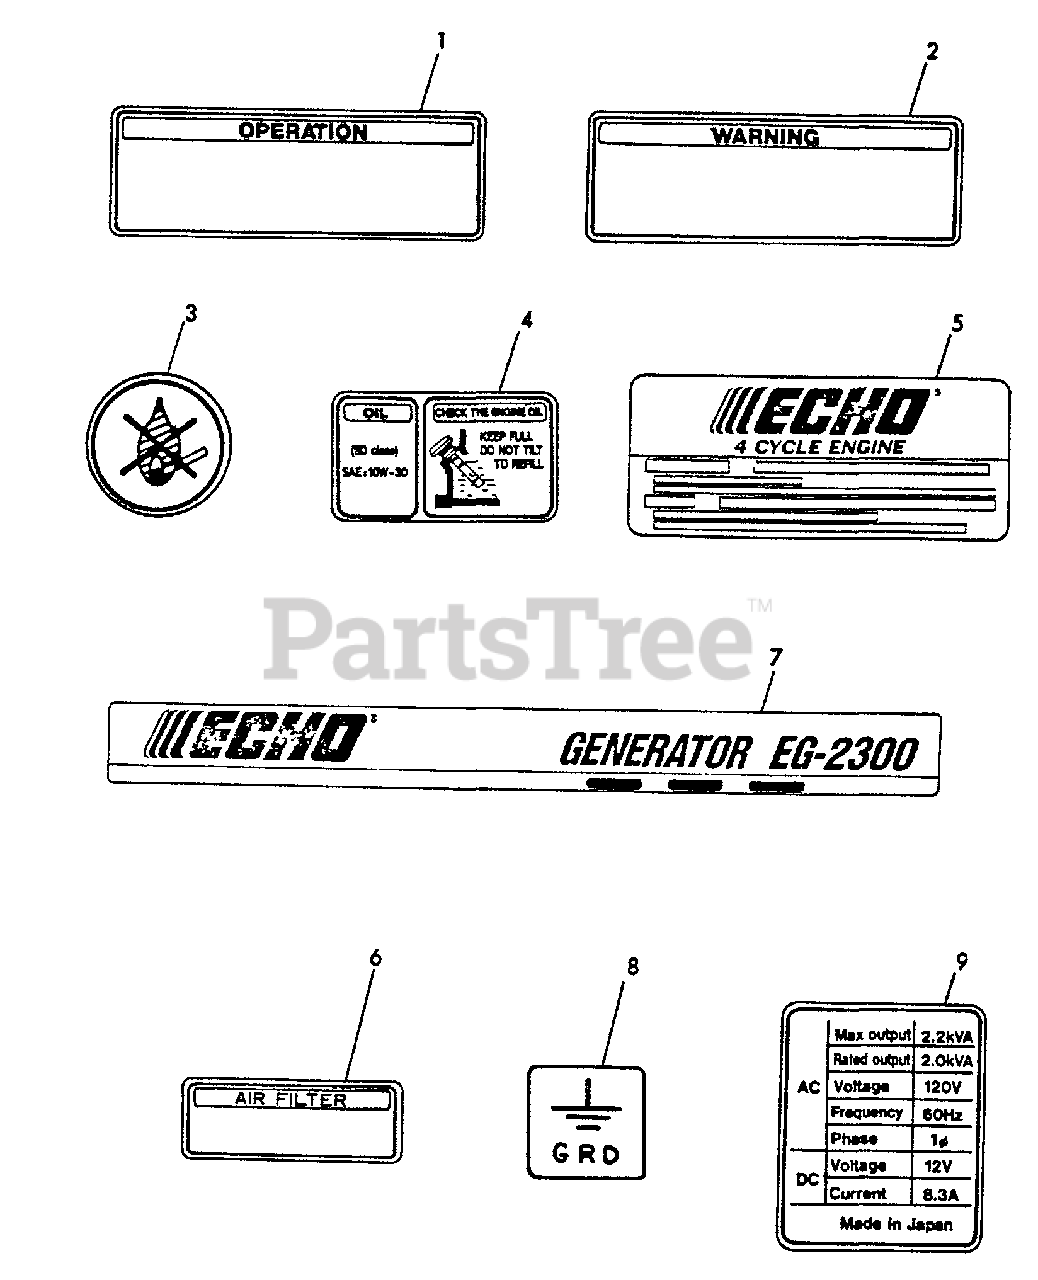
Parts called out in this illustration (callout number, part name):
1	LABEL - OPERATION
2	LABEL - WARNING
3	LABEL - NON FIRE
4	LABEL - OIL
5	LABEL - ECHO
6	LABEL - AIR CLEANER
7	LABEL - MODEL EG2300
8	LABEL - GROUND
9	LABEL - GENERATOR
